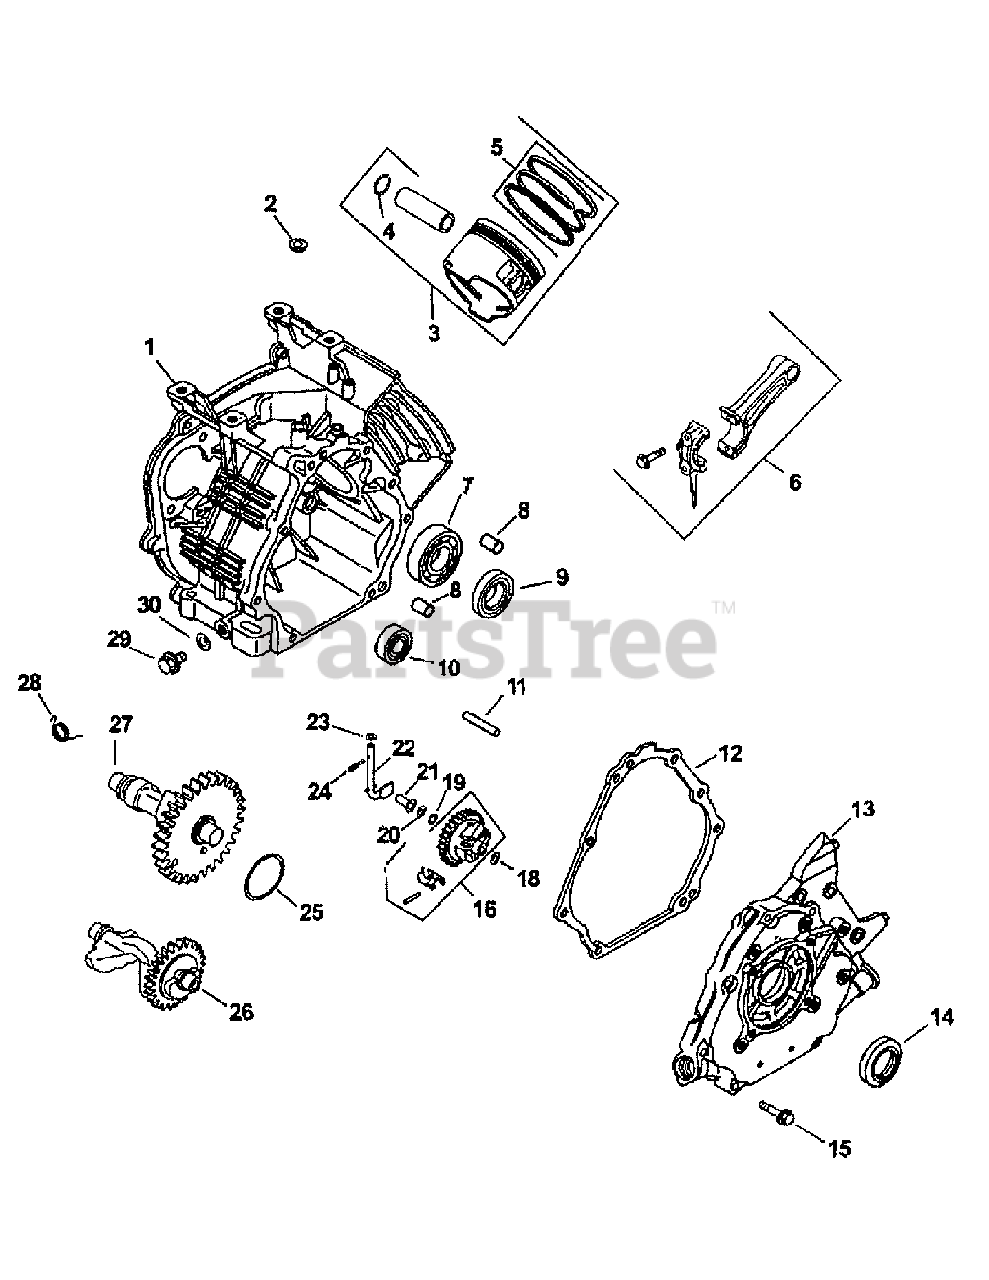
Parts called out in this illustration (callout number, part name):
2	Seal, Governor Shaft
3	Piston w/Ring std.
3	Piston w/Ring 0.25
3	Piston w/Ring 0.50
4	Retainer, Piston Pin
5	Ring Set std.
5	Ring Set 0.25
5	Ring Set 0.50
6	Rod Connecting
7	Bearing
8	Pin, Dowel
11	Shaft, Governor
12	Gasket, Closure Plate
13	I Plate, Closure
15	Screw, Closure Plate
16	Governor Gear
20	Washer, Air Cleaner
22	Shaft, Governor
26	Shaft, Balance
28	Spring, ACR
